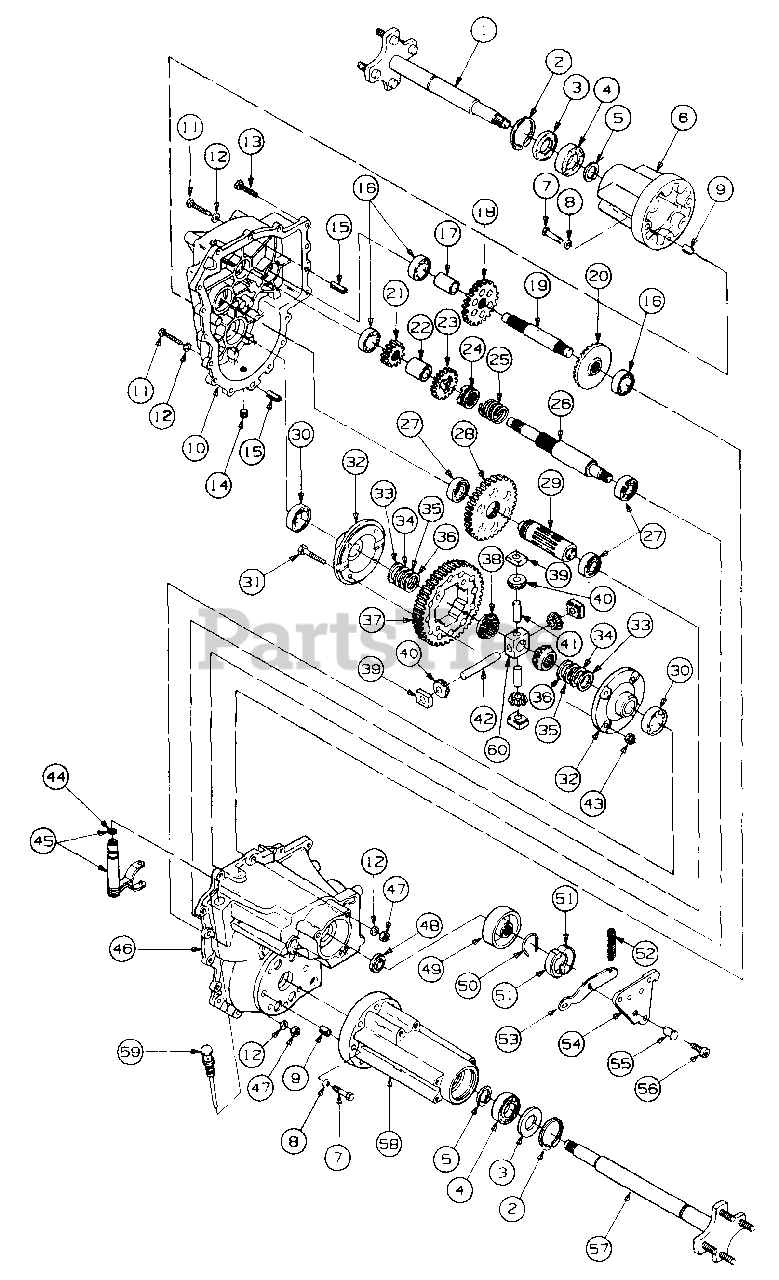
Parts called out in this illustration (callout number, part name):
1	Axle Assy, LH , 11.9" Lg
2	Ring, Inverted Retainer
3	Seal, Oil
4	Bearing
5	Ring, External Retainer
6	Housing, LH, Axle
7	Screw, Hex L-Wash Tapp, 3/8-16 x 1.88 Lg
8	Washer, Bell, 3/8
9	Bushing, Dowel
10	Housing, LH, Differential
11	Screw, Hex Cap, 1/4-20 x 1.5 Lg
12	Washer, Flat, .25 x .62 x .052 Thk
13	Screw, Hex Wash TT-Tapp, 1/4-20 x 1.0 Lg
14	Plug, 1/2-14 NPTF
15	Pin, Slotted Spring, 7/16 x 1.0 Lg
16	Bearing, Ball
17	Spacer, .757 ID x 1.0 OD x 1.460 Lg
18	Gear, 27T Drive
19	Shaft, Drive
20	Gear, 36T Bevel
21	Gear, 16T Spur
22	Spacer, .885 ID x 1.125 OD x 1.400 Lg
23	Gear, 18T Shift
24	Collar, Drive
25	Spring, Compression 1.015 ID x 1.6 Lg
26	Shaft, Shifter
27	Bearing, Ball, .787 x 1.85 x .551 Thk
28	Gear, 42T Spur
29	Shaft, 9T Output
30	Bearing, Ball
31	Screw, Hex Cap, 3/8-24 x 2.0 Lg
32	Cover, Differential
33	Washer, Flat, 1.0 x 1.56 x .010 Thk
34	Washer, Flat, 1.0 x 1.56 x .015 Thk
35	Washer, Flat, 1.0 x 1.56 x .020 Thk
36	Washer, Flat, 1.0 x 1.56 x .040 Thk
37	Gear, 60T Bull
38	Gear, 14T Differential Side
39	Block, Differential Thrust
40	Gear, 10T Differential Pinion
41	Shaft, Gross
42	Shaft, Gross, .500 OD x 3.485 Lg
43	Nut, Hex Lock, 3/8-24
44	O-Ring, 3/8 ID x 1/2 OD x 1/16
45	Yoke Assy, Shift
46	Housing, RH, Differential
47	Nut, Hex Top Lock, 1/4-20
48	Seal, Shift Shaft
49	Drum, Brake
50	Spring, Brake
51	Shoe, Brake
52	Spring, Compression
53	Arm, Brake
54	Plate, Brake
55	Actuator, Brake Shoe
56	Screw Low Hd Cap 3/8-16 x .75 Lg
57	Axle Assy, RH, 15.6" Lg
58	Housing, RH, Axle
59	Dipstick, Oil
60	Block, Differential Pinion
